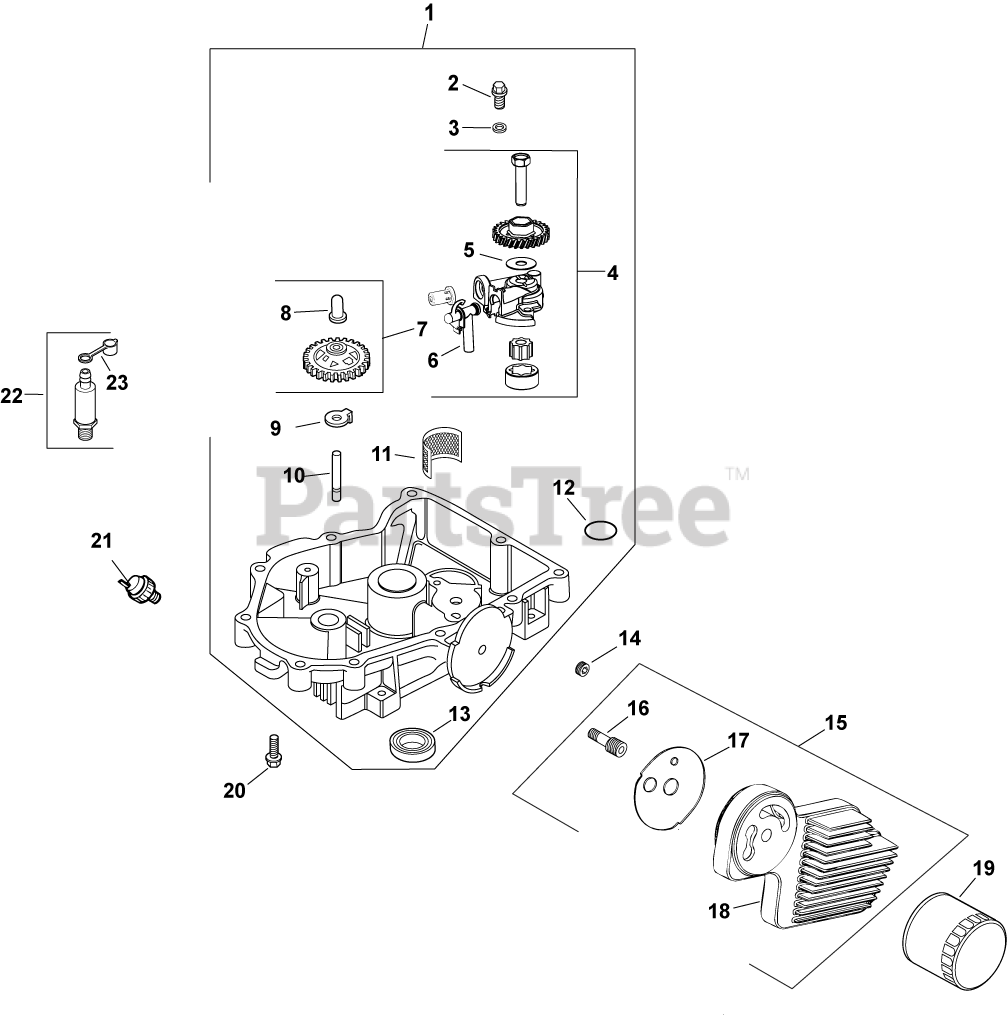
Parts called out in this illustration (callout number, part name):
1	PAN , OIL ASSEMBLY USE 24 199 32-S
2	SCREW,FLG THD FRM M6X1.0X25-(#25086395S)
3	WASHER, FLAT 6 MM
4	PUMP ASSEMBLY, OIL-USE 24 393 53-S
5	KIT, OIL PICK-UP TUBE
6	O-RING, OIL PICK-UP
7	KIT, GOVERNOR GEAR W/PIN
8	PIN, GOVERNOR REGULATING
9	TAB, LOCKING
10	SHAFT, GOVERNOR GEAR
11	SCREEN, OIL
13	SEAL, OIL
14	PLUG, PIPE CTSK 3/8"
15	KIT, OIL COOLER
16	NIPPLE, OIL FILTER
17	GASKET, OIL FILTER ADAPTER USE 24 041 88-S
18	COOLER, OIL ASSEMBLY
19	FILTER, OIL
20	SCREW, FLG M8X1.25X45
21	SENSOR, OIL PSI
22	KIT, OIL DRAIN VALVE
23	CAP, OIL DRAIN VALVE
